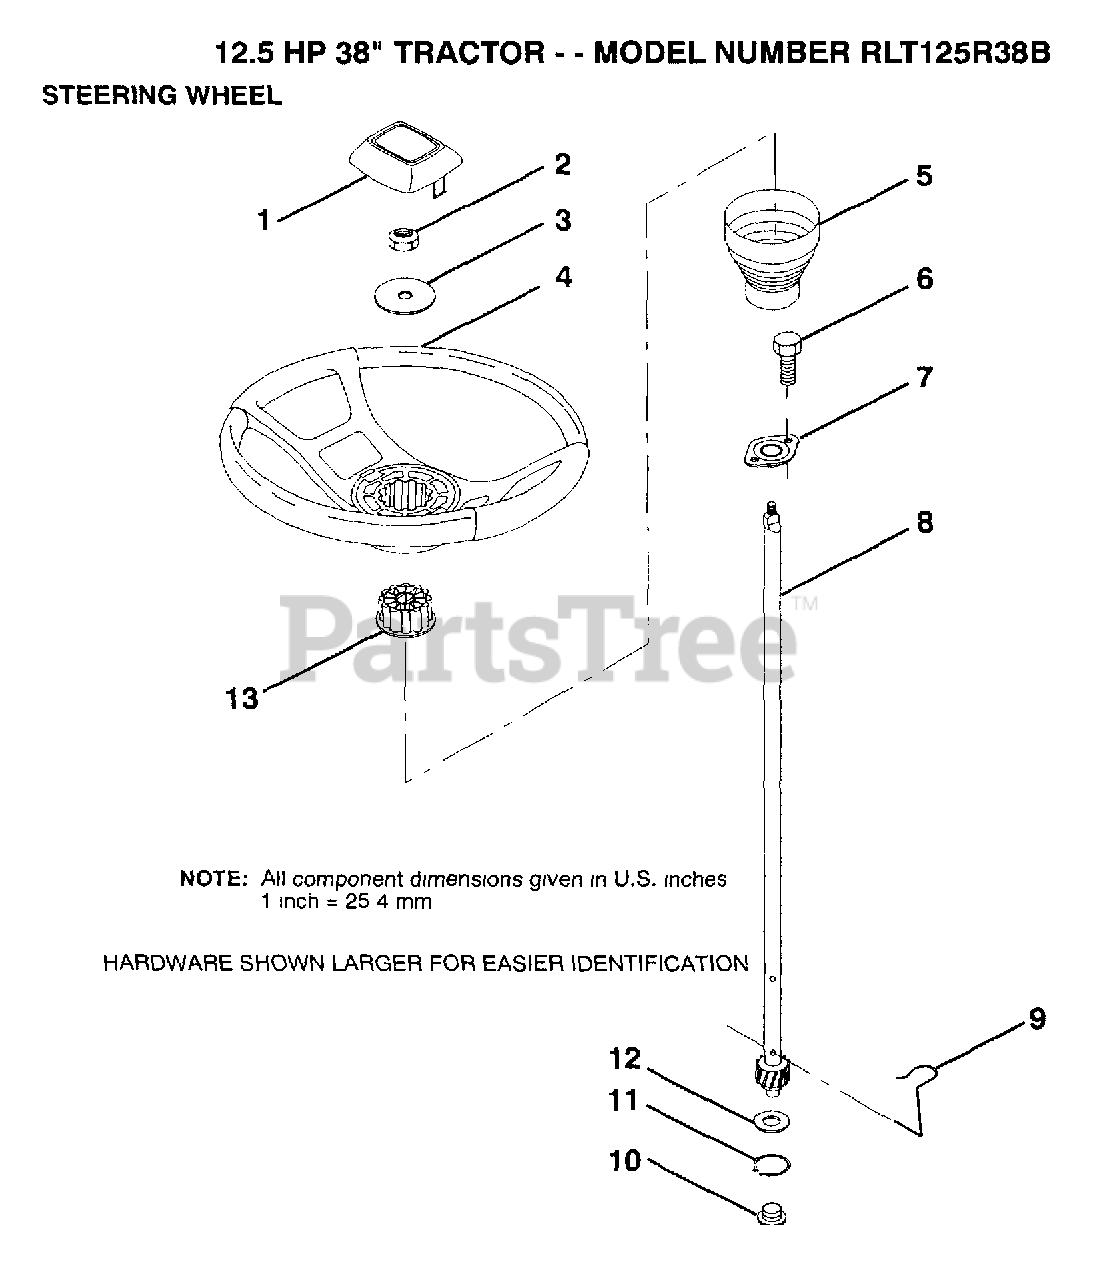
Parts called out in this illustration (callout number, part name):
1	ST WHL INSERT CAP
2	GRIPCO NUT
3	WASHER T
5	SLEEVE STEERING
9	STEERING CLIP
10	BUSHING STEER LWR
11	RING
12	WASHER LT
13	ADAPTER, STEERING WHEEL
